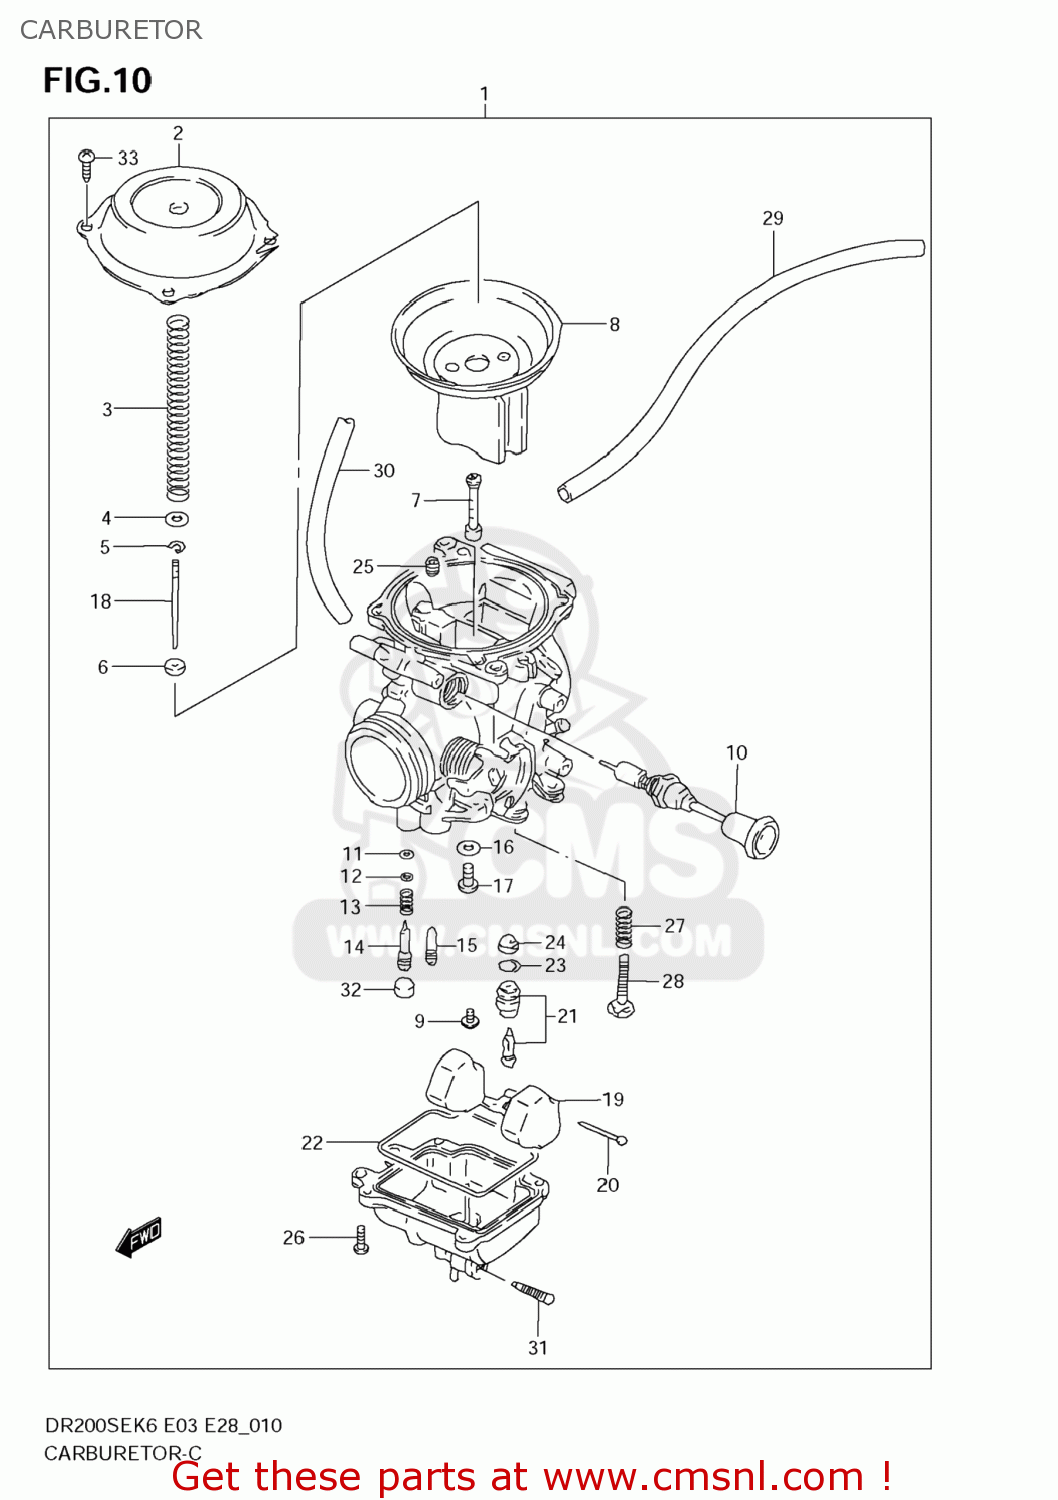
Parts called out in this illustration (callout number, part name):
1	CARBURETOR ASSY
2	COVER,DIAPHRAGM
3	SPRING
4	RING
5	CLIP
6	RING
7	JET,NEEDLE(P-5M)
8	DIAPHRAGM ASSY
9	SCREW
10	PLUNGER ASSY
11	O RING,PILOT AIR SCREW
12	WASHER
13	SPRING
14	SCREW,PILOT
15	JET,PILOT(35)
16	WASHER
17	JET,MAIN(125)
18	NEEDLE,JET(5D77-1)
19	FLOAT
20	PIN,FLOAT
21	VALVE ASSY,NEEDLE
22	O RING,FLOAT CHAMBER
23	O RING,NEEDLE VALVE SEAT
24	FILTER
25	JET,AIR(135)
26	SCREW
27	SPRING,THROTTLE SCREW
28	ADJUSTER
29	HOSE(5X8.2X600)
30	HOSE(4.5X8.5X600)
31	SCREW,DRAIN
32	PLUG
33	SCREW
